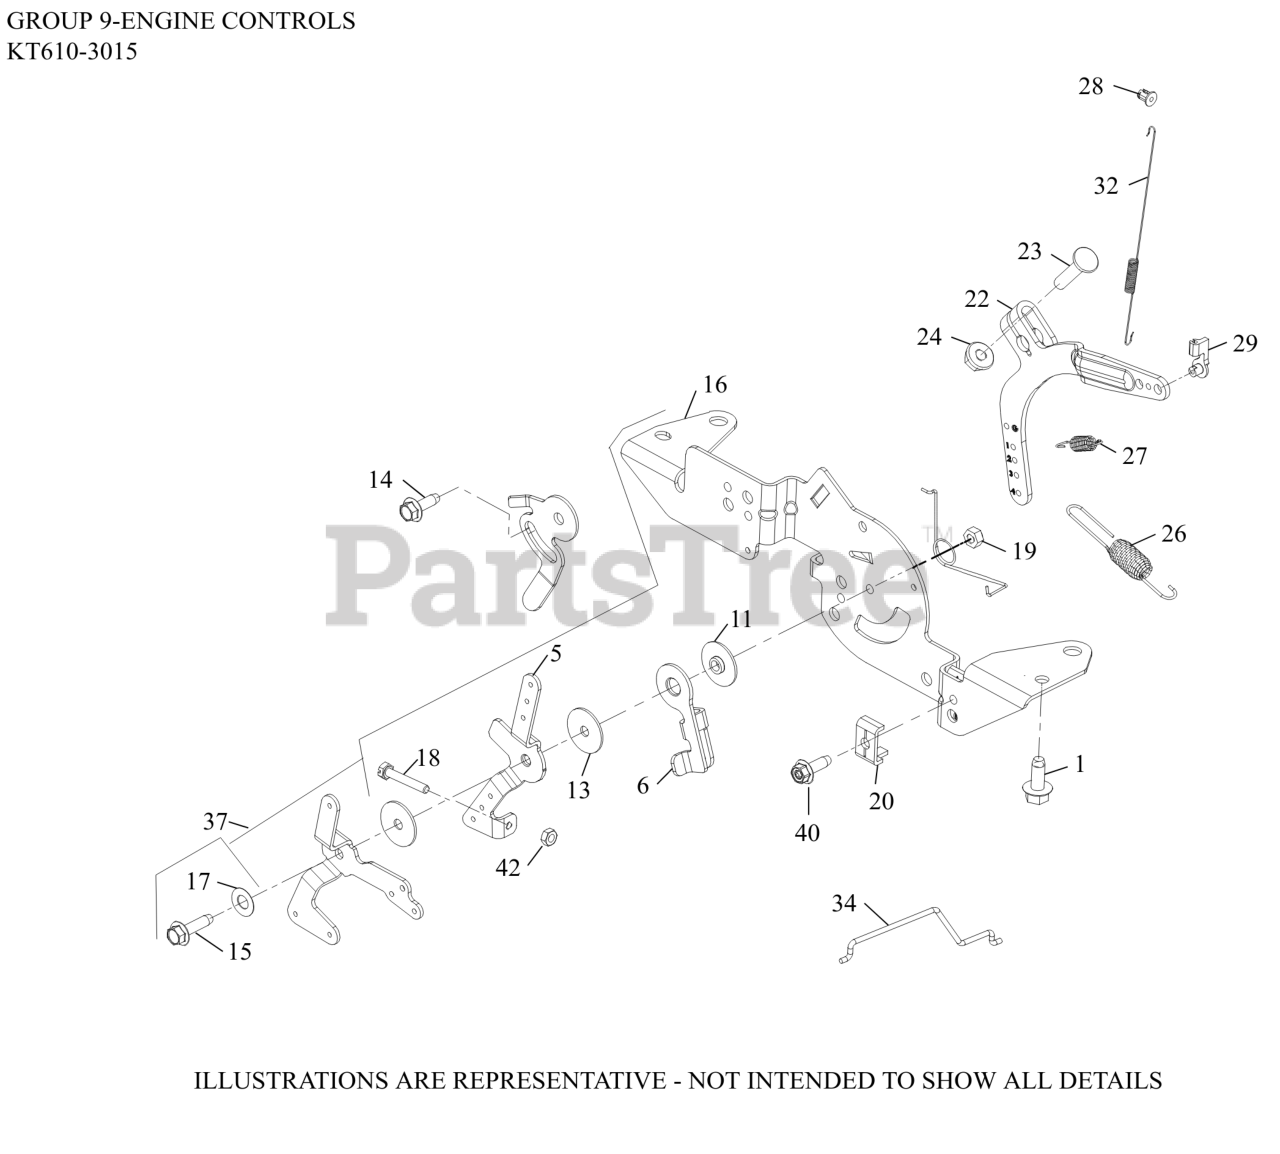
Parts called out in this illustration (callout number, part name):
1	SCREW, THREAD FORMING
2	SPRING, CHOKE RETURN
4	LEVER, CHOKE
5	LEVER, THROTTLE CONTROL
6	LEVER, THROTTLE ACTUATOR
11	SPACER, CONTROL ASSEMBLY
12	WASHER, FLAT 5.5 MM
13	WASHER, FLAT 5 MM
14	SCREW, THREAD FORMING
15	SCREW, THD FRM-USE 25 086 473-S
16	BRACKET, SPEED CONTROL
17	WASHER, SPRING 1/4"
18	SCREW, SLT HD CAP M4X0.7X25
19	NUT, LOCK M5X.8
20	CLAMP, CABLE-(#2523753S)
22	LEVER, GOVERNOR - (#2409069S)
23	BOLT, RD HD SQ NECK M6X1.0X25
24	NUT, FLG M6X1.0
25	LINKAGE, CHOKE
26	SPRING, GOVERNOR (ORANGE)
27	SPRING, GOVERNED IDLE
28	BUSHING, LINKAGE RETAINING
29	BUSHING, THROTTLE LINKAGE
32	SPRING, LINKAGE
34	LINKAGE, THROTTLE
40	SCREW, THREAD FORMING
42	NUT, M4X0.7
